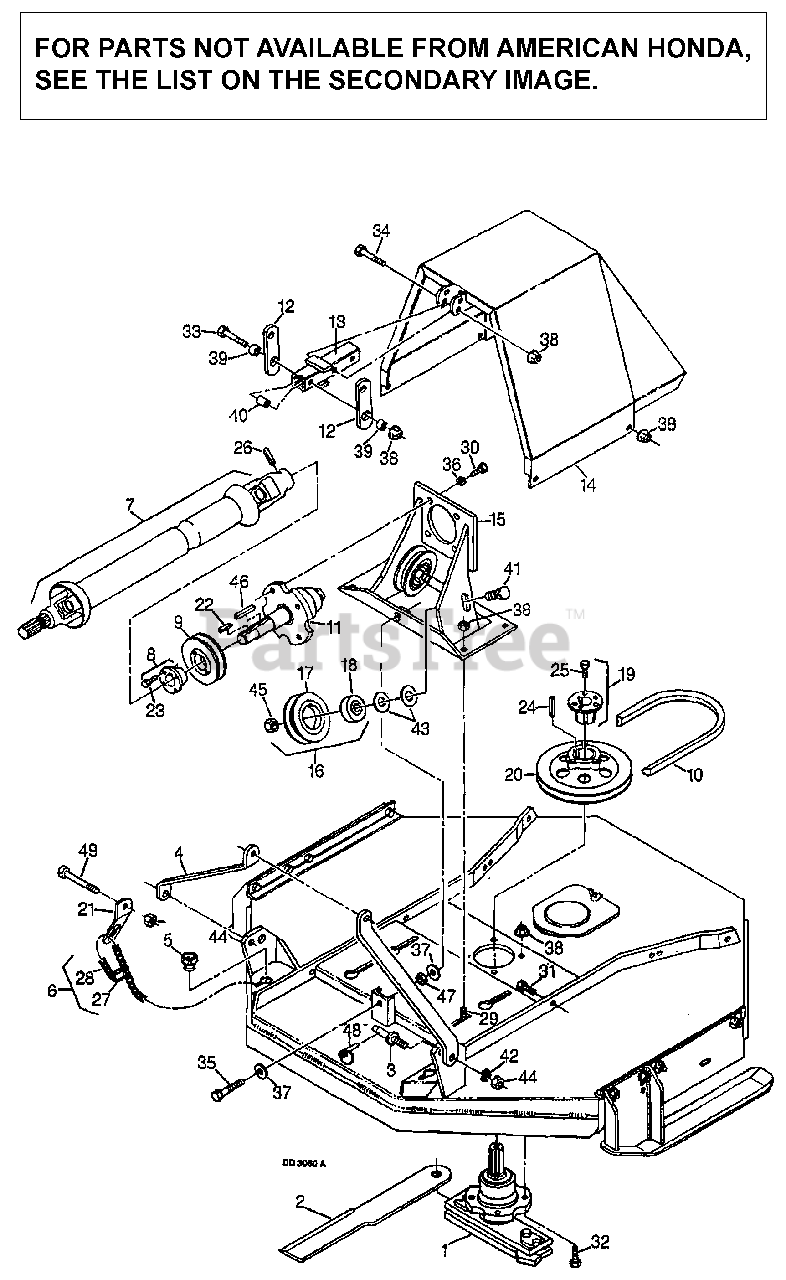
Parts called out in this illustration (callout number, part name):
1	SPINDLE, BLADE CW
3	PIN, MOUNTING
4	BAR, A-FRAME
5	PLUG, CAP
6	CHAIN, CHECK
10	V-BELT (W44)
11	SPINDLE ASSY., DRIVE
12	LINK, TOP PIVOT
13	TUBE ASSY., TOP LINK
14	SHIELD, DRIVE
15	BRACKET ASSY., IDLER
16	PULLEY, IDLER
17	IDLER, V-GROOVE
18	BEARING, BALL
21	BRACKET, CHECK CHAIN
22	KEY (1/4 X 1/4 X 1-1/4)
24	KEY (1/4 X 3/8 X 2)
30	SCREW, CAP
31	SCREW, CAP
32	SCREW, CAP
35	SCREW, CAP (1/2 X 1-1/2")
38	NUT, LOCK
39	SLEEVE, HT (1/2 X 3/4 X 3/8)
40	SLEEVE, WALL (17GA)
47	NUT, HEX. (1/2")
